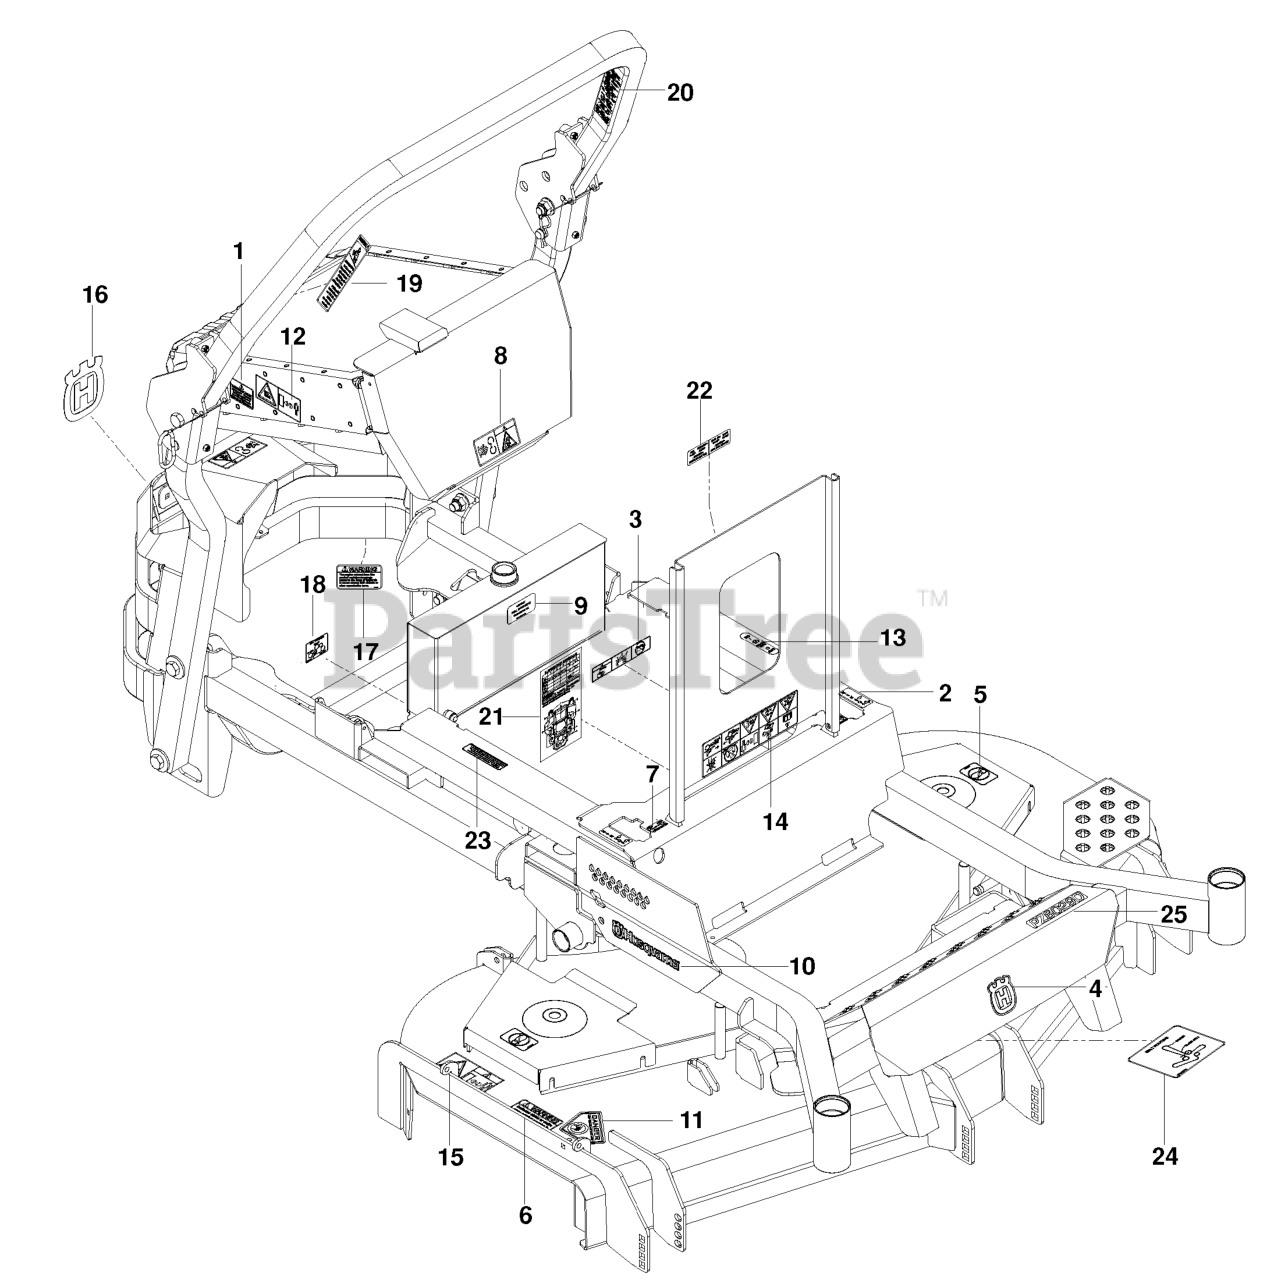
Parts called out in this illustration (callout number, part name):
1	DECAL, DEBRIS SCREEN
2	DECAL, MOTION CONTROL
3	EURO DECAL-BATTERY WARNIN6
4	DECAL, CROWN H 70MM
5	DECAL, NO STEP
6	DECAL, CAUTION
7	DECAL, F.S.T.
8	DECAL, BELT DRIVE
9	DECAL, OIL TANK
10	DECAL.HOOD.LOGO.ORANGE.HUSQVAR
11	DECAL, CPSC
12	DECAL, HOT
13	DECAL, PARK BRAKE
14	DECAL, WARNING
15	DECAL, EURO SEVERING
16	DECAL, CROWN H, 110MM
17	DECAL, PROP. 65
18	DECAL, HYDRO BELT
19	DECAL, ROPS, WARNING
20	DECAL, ROPS, DIESEL
21	DECAL, SERVICE, DIESEL
22	DECAL, FUSE, DIESEL
23	DECAL, WARNING SPARK ARRESTOR
24	DECAL, BELT ROUTING
25	DECAL, PZ6029D
